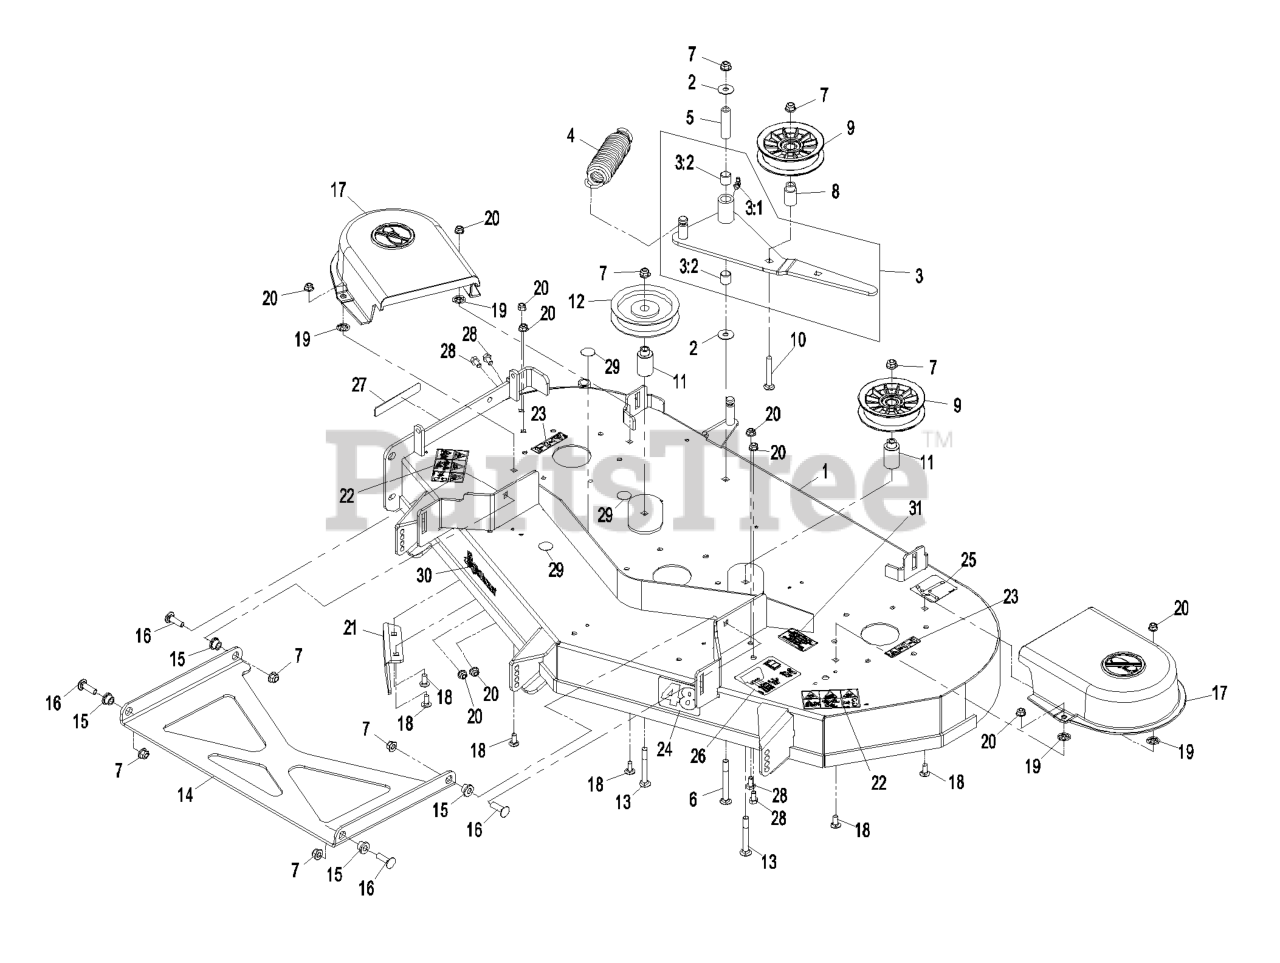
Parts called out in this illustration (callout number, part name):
1	48 INCH DECK ASM
3	IDLER ARM ASM
3:1	FITTING-GREASE, 90 DEG
3:2	SLEEVE-BEARING
5	BUSHING-PIVOT, IDLER
6	SCREW-CARR
7	NUT-HF, NI
8	BUSHING-IDLER
9	SHEAVE AND BEARING ASM
10	SCREW-CARR
11	BUSHING-IDLER
13	BOLT-CARRIAGE
14	STRUT-DECK
15	BUSHING-FLANGED
16	BOLT-CARR
17	SHIELD-BELT
18	SCREW-CARR
19	RING-RETAINING, BOLT
20	NUT-HF, NI
21	BAFFLE-DISCHARGE
22	DECAL-DANGER
23	DECAL-WARNING, BELT SHIEL
24	DECAL,DECK 48
25	DECAL-ROUTING, BELT
26	DECAL-ROLLER, ANTI-SCALP
27	DECAL-DANGER
28	SCREW-HH
29	DECAL-HOLE COVER
31	DECAL,BLADE TORQUE
